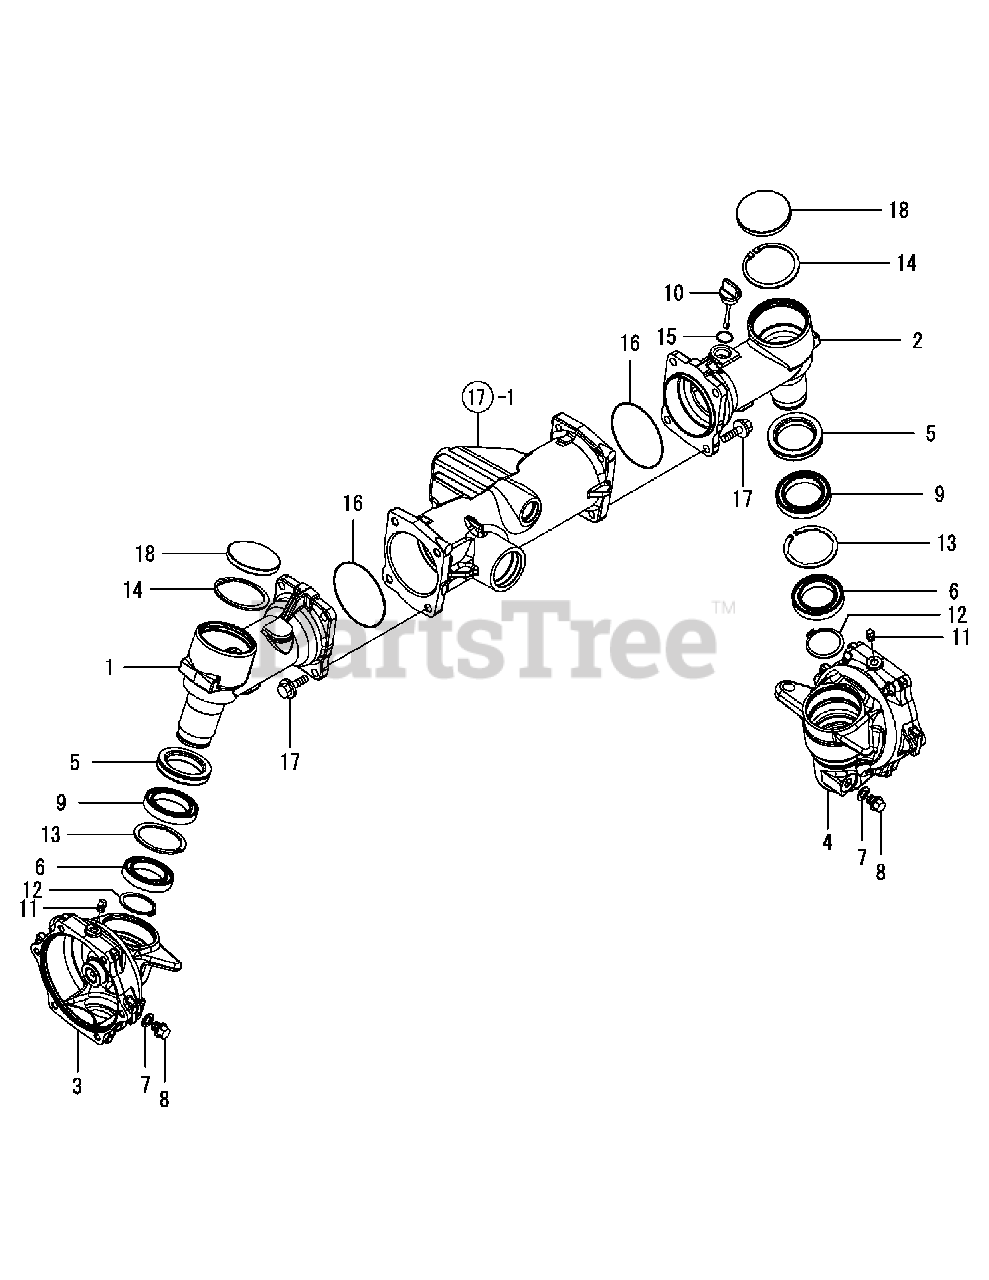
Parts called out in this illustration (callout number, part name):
1	CASE L, FRONT GEAR
2	CASE R, FRONT GEAR
3	BOX L, FRONT GEAR
4	BOX R, FRONT GEAR
5	SEAL QLN 50721013
7	SEAL, GASKET 20X12X2
8	BOLT M 12X 12 PLATED
10	GAUGE, OIL LEVEL
15	O-RING 1A P-18.0
16	O-RING 1A S-85.0
17	BOLT M10X 30 PLATED
18	CAP, SEALING 72
